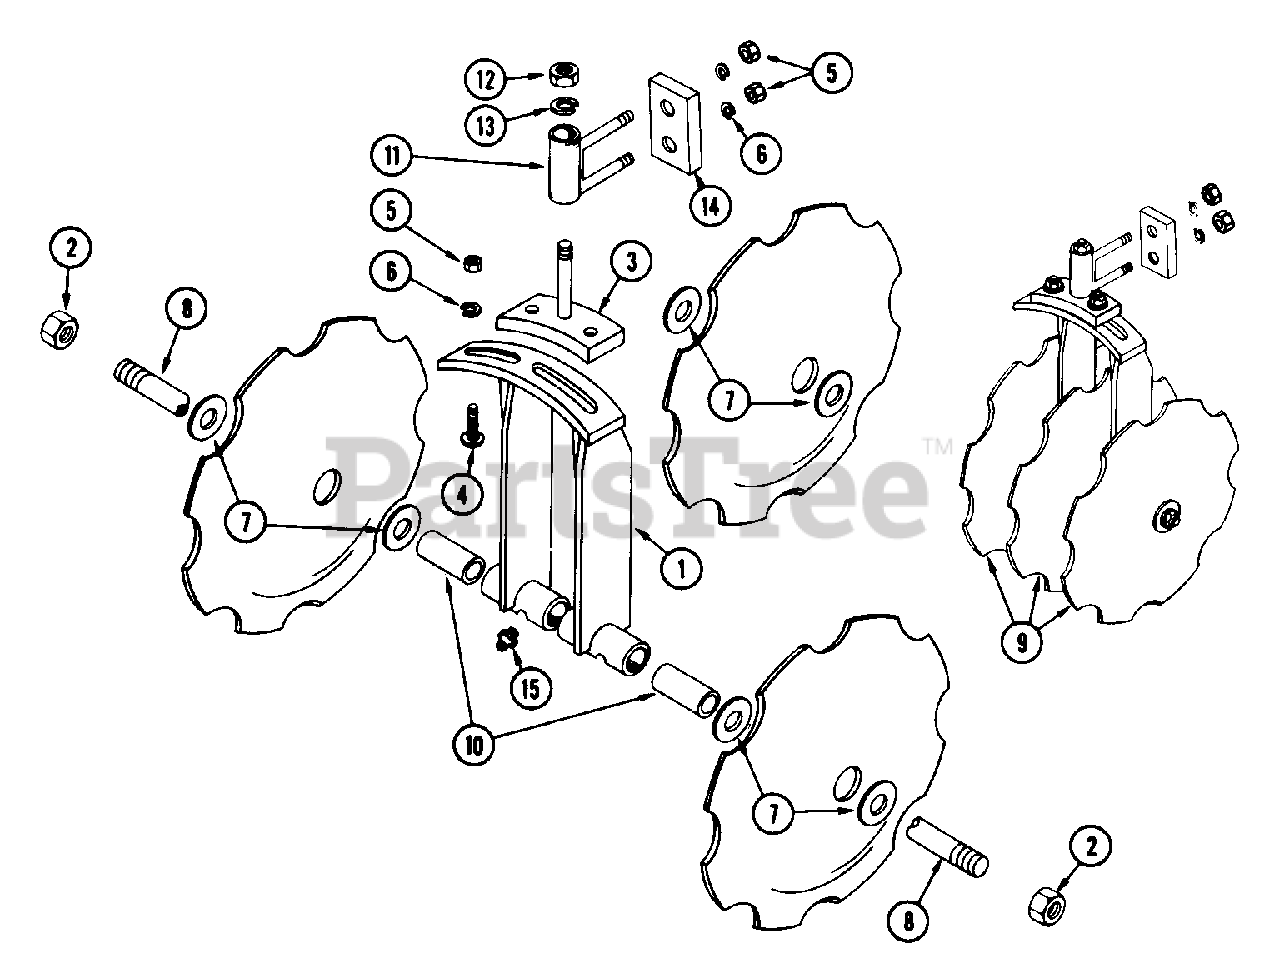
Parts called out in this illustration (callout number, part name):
1	LOWER ROCKING BOASTER
2	NUT-LK-CTR .75-10 PL
3	UPPER ROCKING BOASTER
4	BLT-RDHDSQNK .50-13X2.50 PL
5	NUT .50-13 PL
6	WSHR-LK .500X.151 HVY PL
7	WSHR-FL-STL.812X1.500X.139
8	ARBOR BOLT
10	BSHG-SLV (ND)
11	GANG RETAINER BRACKET
12	NUT-JAM .875-9 (ND)
13	WSHR-LOCK .875 MED PL
14	BRACKET RETAINER STRAP
15	SPIN DRIVE ZERK FITTING
